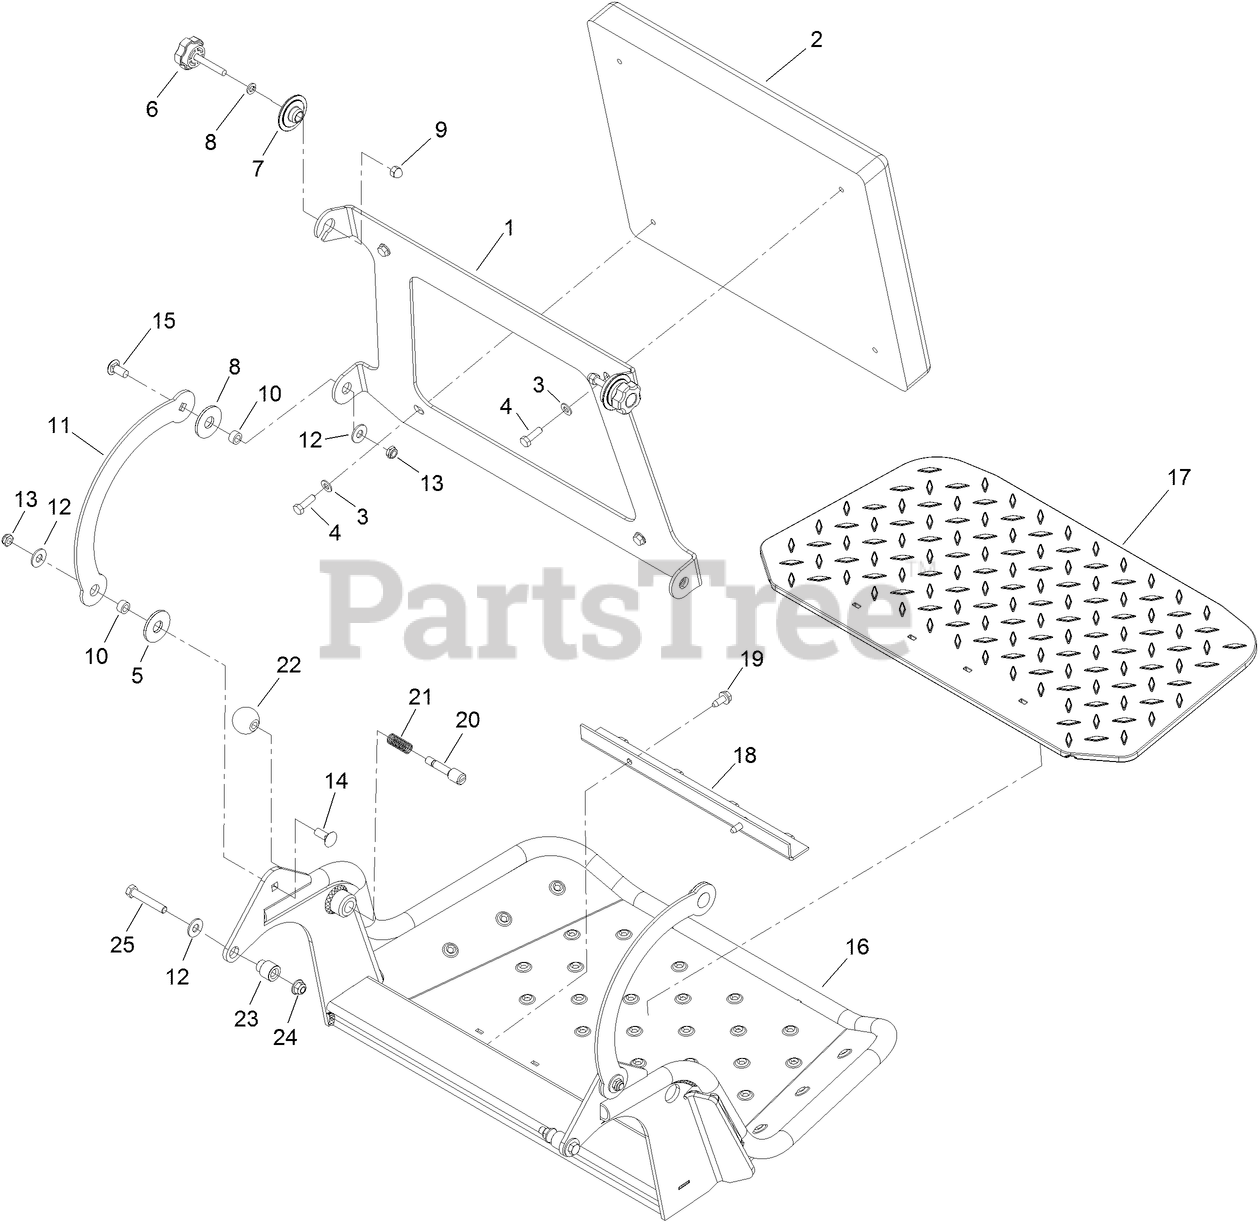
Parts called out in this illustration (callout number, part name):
1	HINGE-PAD
2	PAD-CUSHION
3	WASHER-PLAIN
4	SCREW-HH
5	WASHER-FRICTION, COMPOSITE
7	SLIDE-BUSHING
8	WASHER-LOCK
9	NUT-ACORN
10	SPACER
11	LINK-PAD
12	WASHER-FLAT
13	NUT-LOCK, NI
14	BOLT-CARR
15	SCREW-CARR
16	PLATFORM
17	MAT-FOOT
18	CLAMP-SHIELD
19	SCREW-HWHTF
20	PIN-LATCH
21	SPRING
22	KNOB-BALL
23	BUSHING-FLANGED
24	NUT-HF, NI
25	SCREW-HH
